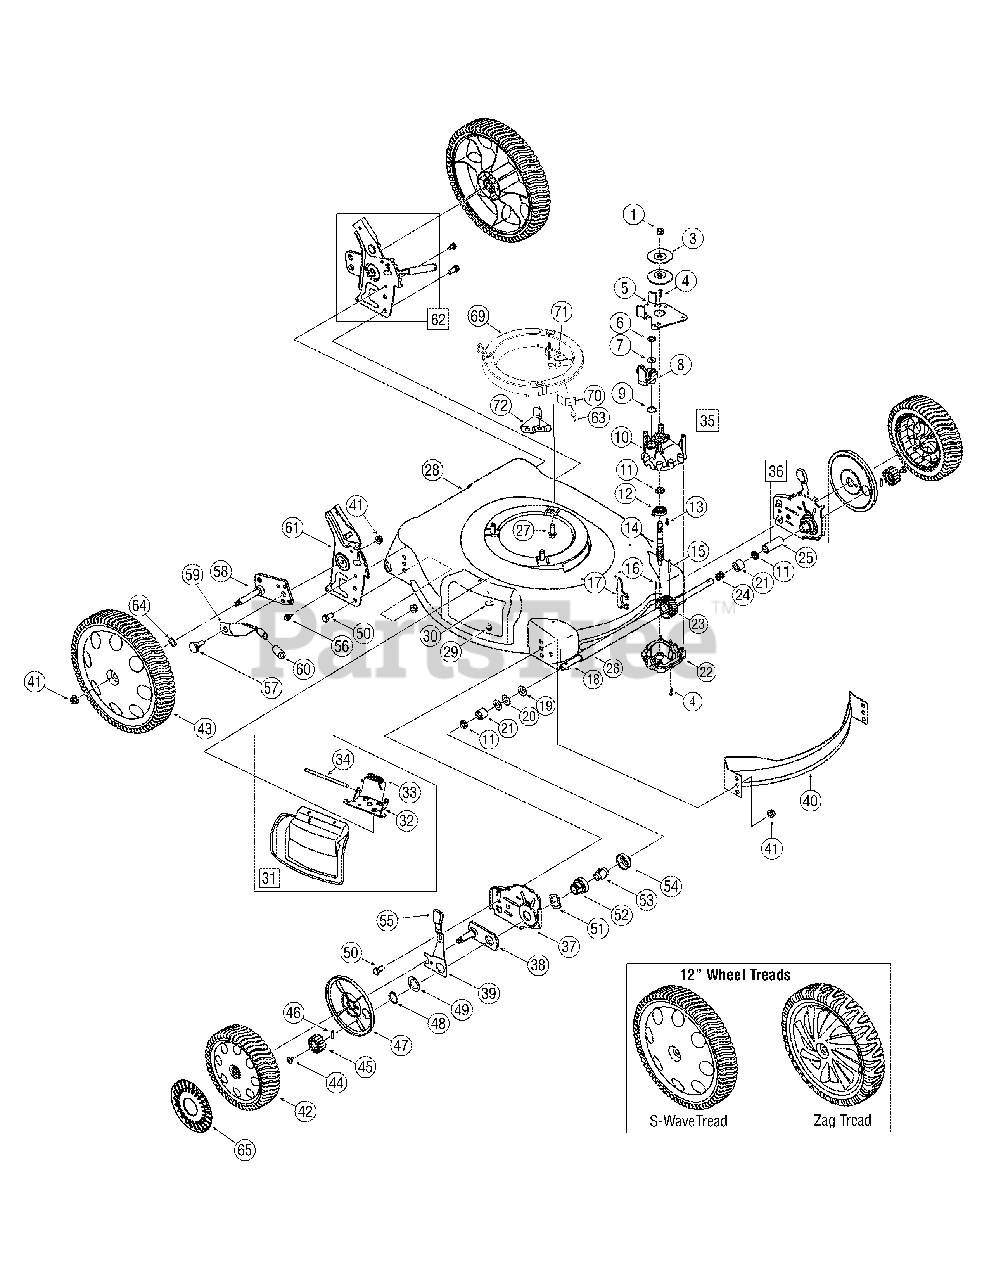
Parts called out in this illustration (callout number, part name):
1	Flanged Lock Nut 5/16-18 Gr. F Nylon
3	Pulley 2.5 OD
5	Transmission Bracket
6	Push Nut
7	Slotted Washer
10	Upper Housing
11	Oil Seal
14	Pinion Shaft
15	Dowel Pin
18	Output Shaft
19	Flat Washer
21	Plastic Bushing
22	Lower Housing Ass’y
23	28 Tooth Gear
24	Compression Spring
25	Sleeve Spacer 1.8" Lg.
26	Sleeve Spacer 9.10" Lg.
27	Hex Wash TT Sems Scr 3/8-16 x 1.875
29	Hex Wash S-Tapp Scr 1/4-20 x .50
30	Cupped Washer .265 ID x .75 OD x .062
31	Complete Mulch Plug
32	Chute Hinge
33	Torsion Spring
34	Hinge Pin
35	Transmission Ass’y Complete
36	RH Height Adjustment Assembly
36	LH Height Adjustment Assembly
37	Height Adjuster Plate - RH
37	Height Adjuster Plate - LH
38	Height Adjuster Pivot Plate Ass'y
39	Spring Lever Front RH
39	Spring Lever Front LH
40	Front Baffle
41	Hex L-FlangeNut 3/8-16 Gr. F, Nylon
42	Wheel Ass'y 8 x 2.125 Gear Zag
43	Wheel Ass'y 12 x 2.125 Gear Zag
44	Pan Scr. 1/4-20 x .390
45	Spur Gear 14T RH
45	Spur Gear 14T LH
47	Wheel Dust Cap
48	Snap Ring for 1.0" shaft
49	Flat Washer 1.5 OD x .03
50	Hex Cap Screw 3/8-16 x .75
51	Wave Washer
52	Bearing Support
53	Bearing Sleeve
54	Bearing Retainer
55	Height Adjuster Knob
56	Hex Wash Hd TT Scr. 1/4-20 x .625
57	Shoulder Screw .50 Dia. X .385
58	Pivot Arm Assem bly - RH
58	Pivot Arm Assem bly - LH
59	Rear Spring Lever
61	RH Handle Bracket
61	LH Handle Bracket
62	LH Handle Bracket Assembly
62	RH Handle Bracket Assembly
64	Spring Washer .50 ID x 1.0 OD x .022
65	Hub Cap Grey Radial
